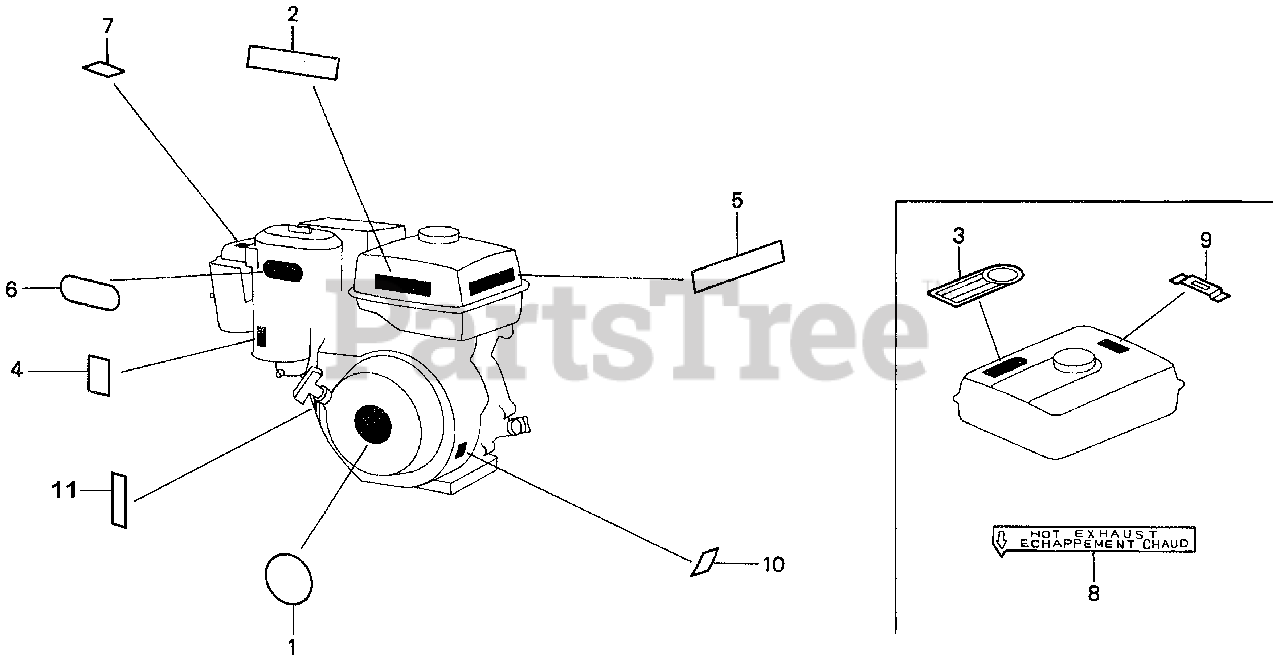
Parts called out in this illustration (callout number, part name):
1	EMBLEM
3	MARK, CAUTION (ENGLISH/FRENCH)(SPANISH)
4	MARK, CHOKE
6	MARK, AIR CLEANER
8	MARK, EX. CAUTION (ENGLISH/FRENCH)
9	PLATE, FUEL INDICATION
10	MARK, OIL CAUTION
